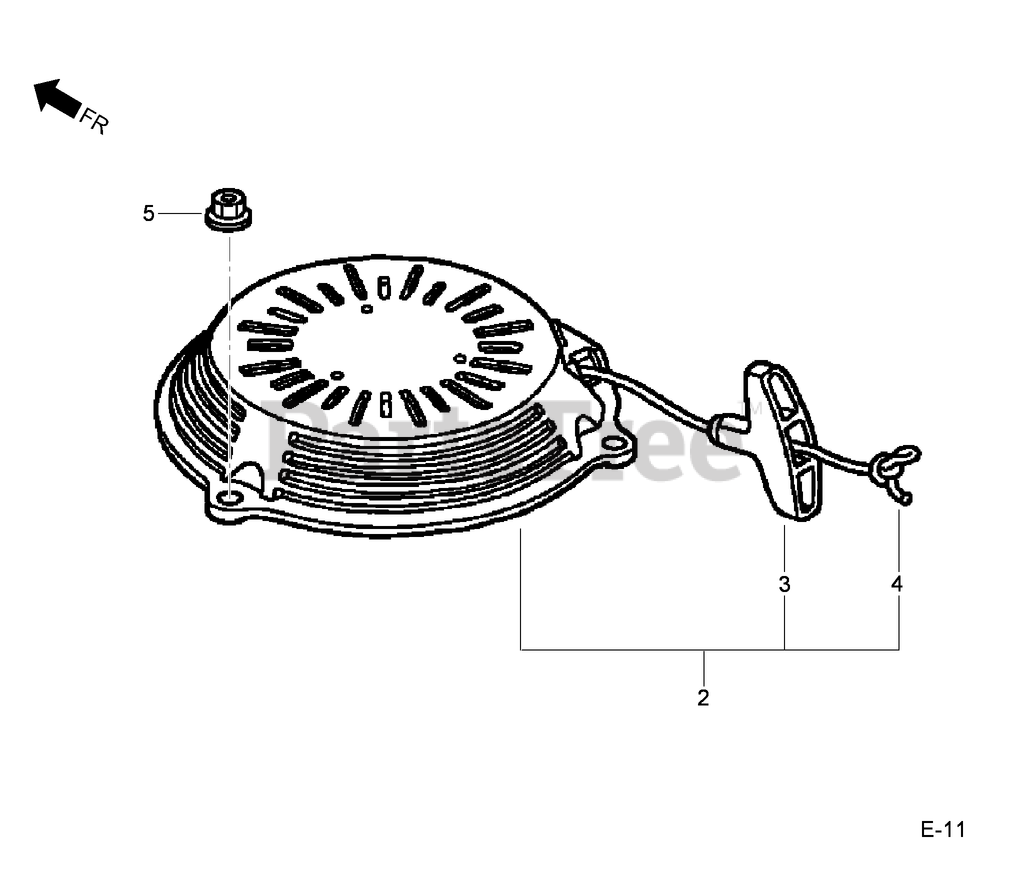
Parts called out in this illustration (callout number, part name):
2	RECOIL STARTER ASM (N H1) (LONG ROPE) (BLACK)
2	RECOIL STARTER ASM (T98) (LONG ROPE) (MTD RED)
3	GRIP-STARTER
4	ROPE-STARTER, RECOIL (BLACK) (LONG TYPE)
5	NUT-FLANGE (6MM)
